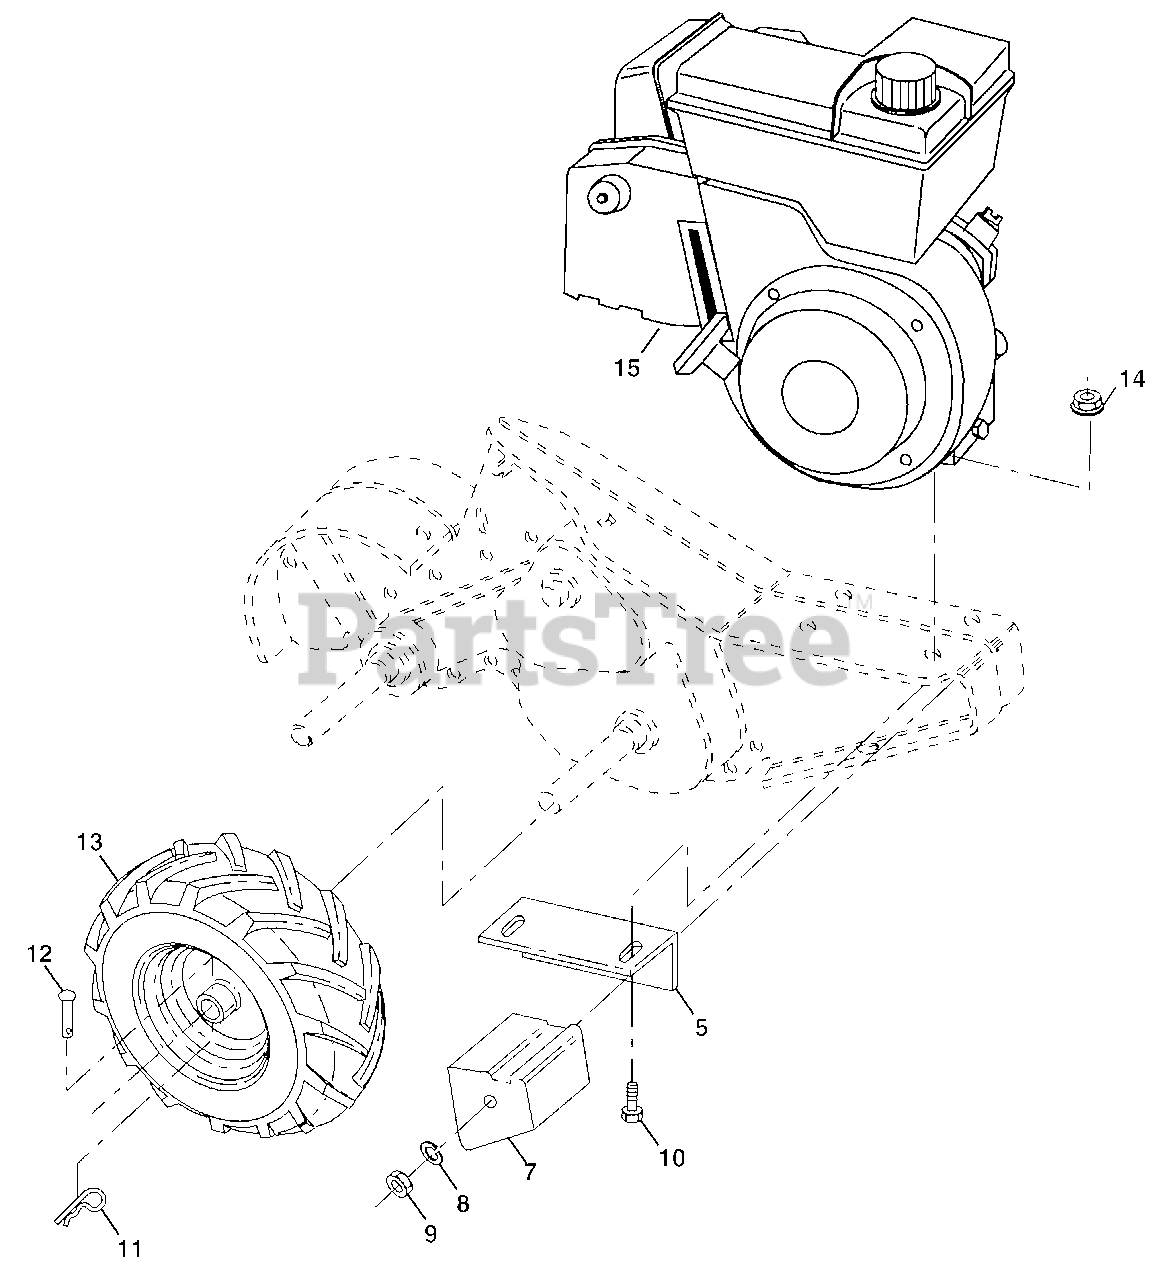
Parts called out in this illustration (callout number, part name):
5	Bracket, Reinforcement
7	Counter Weight, R.H.
8	Washer, Lock 3/8
9	Nut, Hex 3/8-16
10	Bolt, Hex 5/16-18 x 1-1/2
11	Clip, Hairpin
12	Rivet, Drilled
13	Tire
13	Rim
13	Tire Valve
14	Nut, Hex Flange
